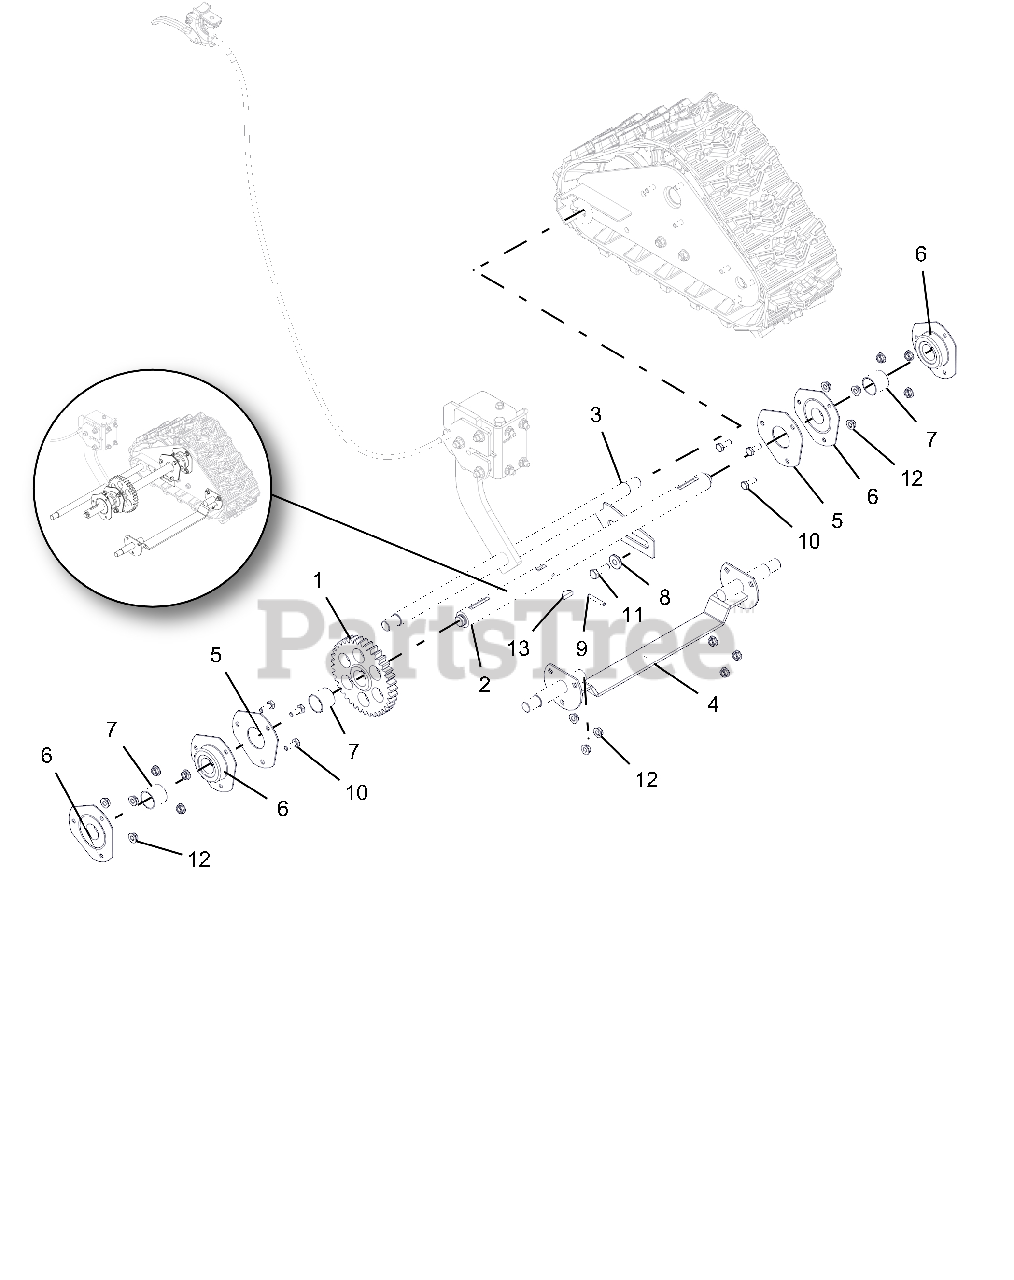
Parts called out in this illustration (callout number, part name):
1	GEAR, SPUR
2	AXLE, TRACK-DELUXE
3	AXLE, REAR - DELUXE TRACK
4	AXLE, FRONT-COMPACT TRACK
5	PLATE, BEARING SPACER
6	BRG-FLG 1.003/1.000 3 BOLT
7	BSHG-SLV, 1.012X1.125X1.00
8	BSHG-FLG .325X.499X.3X.875
9	PIN-ROLL .188X1.25
10	@BLT-HEX .25-20X.75 GR5 YWZC
11	@BLT-HEX .31-18X1.00 GR5 YWZC
12	@NUT-LK-CTR-FLG .25-20 YWZC
13	KEY-WDRF .25X.750X.313 SAE91
